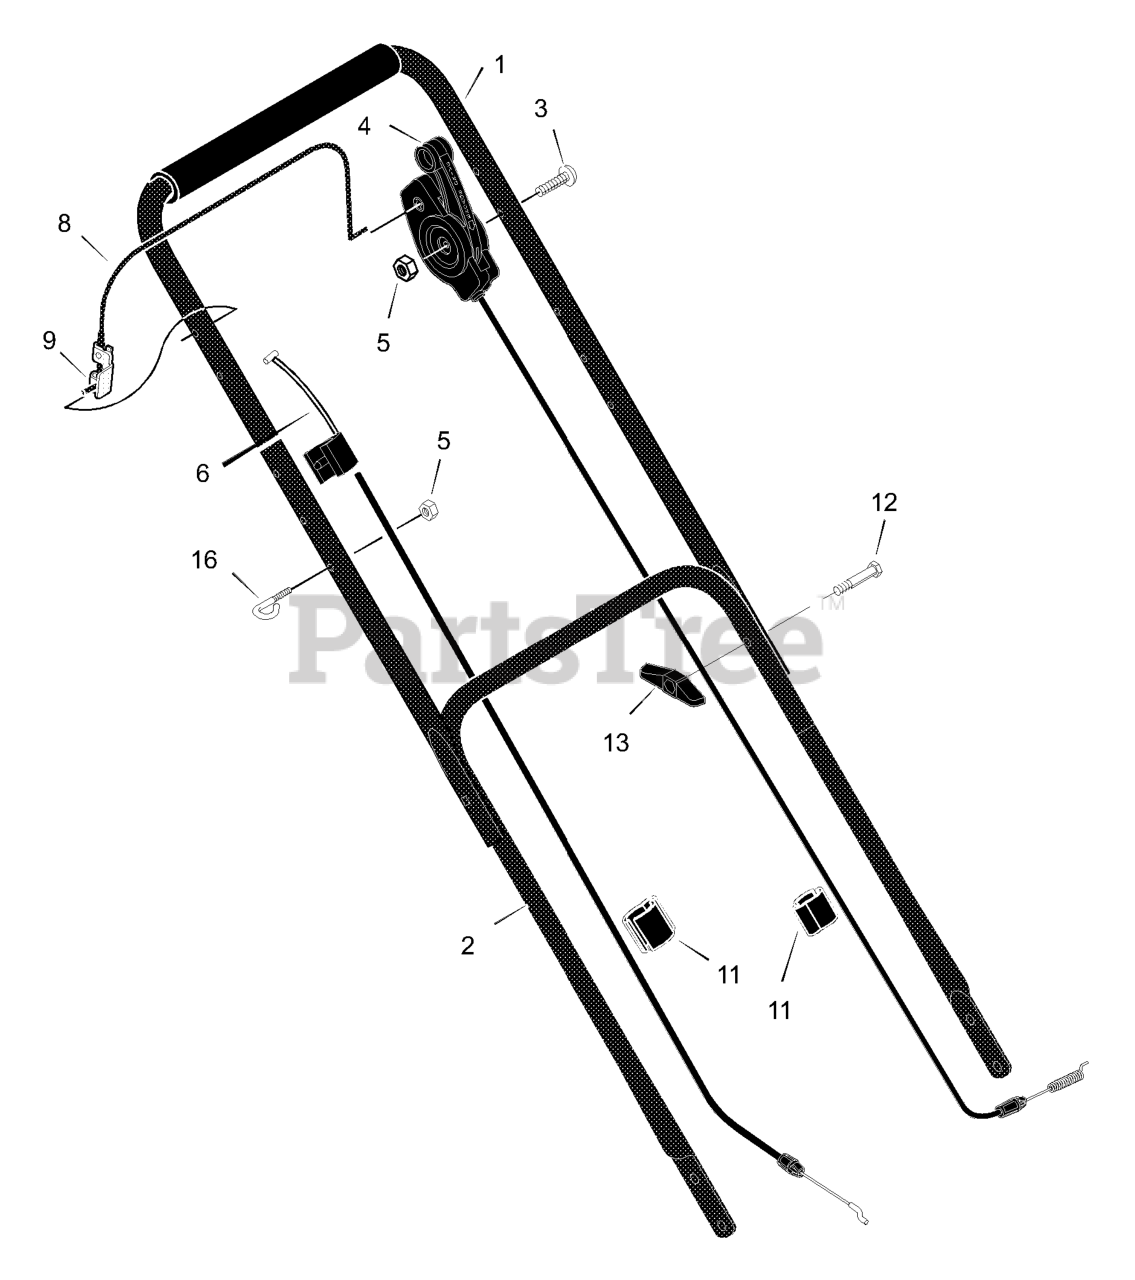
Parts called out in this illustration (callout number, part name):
1	Engine
1	Handle, Upper (Black)
2	Handle, Lower (Black)
4	Control, Drive
5	Locknut
6	Cable, Stop
8	Lever, Stop
9	Bracket, Stop Lever
11	Fastener, Cable
13	Knob
16	Guide, Rope
